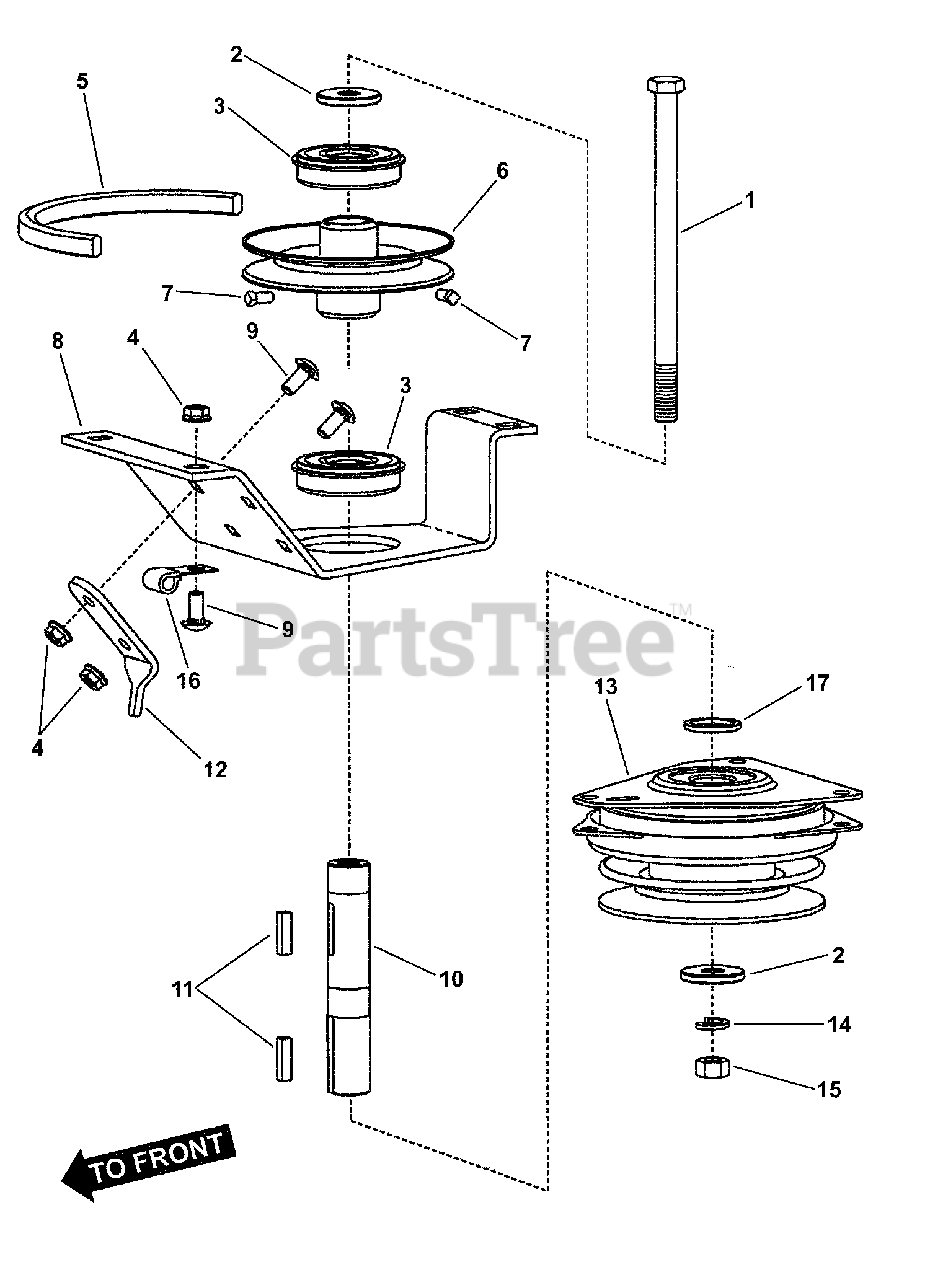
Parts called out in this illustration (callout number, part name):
1	BOLT, 7/16-20 x 8" Hex Head, GR 5
2	WASHER, .468 I.D. x 1.50 O.D. x .188 Flat
3	BEARING, 6305 w/Snap Ring
4	NUT, 5/16-18 Hex Flange Lock, GR 5
5	V-BELT, 5L Sect. Cog, 50.170" effective length
6	PULLEY, Jackshaft
7	SCREW, 1/4-20 x 1/2" Set w/Patch
8	SUPPORT, Jackshaft- TG 2000
9	BOLT, 5/16-18 x 3/4" Short Neck Carriage, GR 5
10	JACKSHAFT
11	KEY, 1/4" Square x 1"
12	BRACKET, Anti-Rotation- TG-2000
13	CLUTCH, Warner TG-2000 (12V)
14	WASHER, 7/16" Split Lock
15	NUT, 7/16-20 Hex, GR 5 or B
16	WIRE CLIP 7/16", Vinyl Covered
17	SPACER, Jackshaft, Warner Clutch
